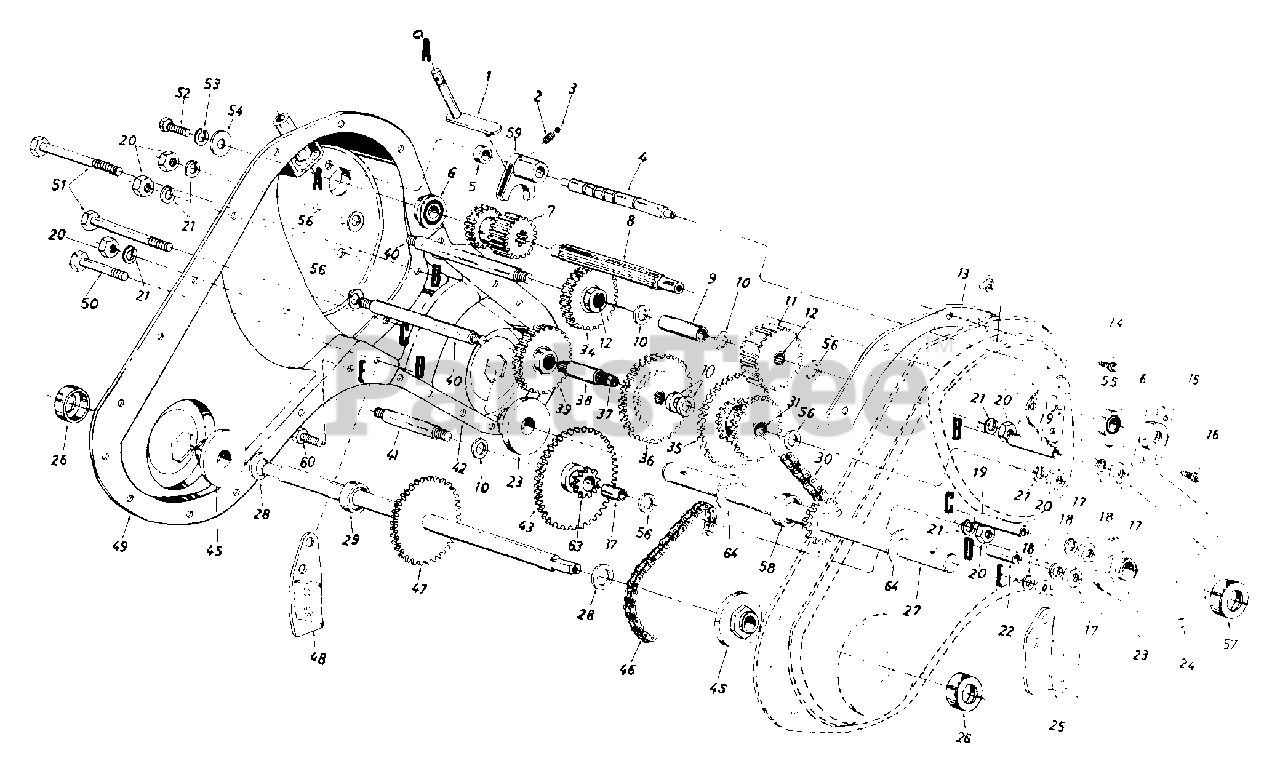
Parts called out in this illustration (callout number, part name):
1	Shifting Bracket Ass'y.
2	Compression Spring .50" Lg.
3	Ball Detent .250" Dia.
4	Detent Shaft 1/2" Dia.
5	Spacer .505" I.D. x .88" O.D.
6	Ball Brg. .62" I.D. x 1.38"
7	Spur Gear 16T (Input)
8	Input Spline Shaft 7/8"
9	Spacer .657" I.D. x 2.85" Lg.
10	Fl-Wash. .640" I.D. x 1.24"
11	Spur Gear 30T 7/8" I.D.
12	Needle Bearing 5/8" I.D.
13	Gasket - Trans. Hsg.
14	Hex S-Tap Scr. 1/4-20 x .5"
15	1-3/8" Dia. Bearing Housing
16	Hex TT-Tap Scr. 1/4-20 x .75"
17	Hex Nut 5/16-18 Thd.
18	L-Wash. 5/16" I.D.
19	Spacer 1.56" Lg.
20	Hex Nut 7/16-20 Thd.
21	Bell-Wash. .45" I.D. x 1.0"
22	Spacer 1.015" Lg.
23	Tine Shaft Brg. 1.002 x 2.50
24	Trans. Housing Ass'y. - L.H.
27	Tine Shaft Ass'y. 1" O.D.
28	Fl-Wash. .76" I.D. x 1.5" O.D.
29	Spacer .75" I.D. x .50" Lg.
30	Chain #50 5/8 Pitch x 52 Links - Endless
31	Needle Bearing 5/8" I.D.
32	Snap Ring
33	Taper Cap Plug
34	Spur Gear 30T 12/16" I.D
35	30/44T Gear Ass'y. Comp.
36	Spur Gear 44T
37	Sleeve Bearing
38	Gear Hub 3/4" I.D. x 3" Lg.
39	Spur Gear 30T 1.0" I.D. x 1/2" W
40	Jack Shaft 5/8" Dia. x 5"
41	Jack Shaft 5/8" Dia. x 2.38"
42	Trans. Housing Ass'y. - R.H.
43	Spur Gear 55T
45	Wheel Brg. .752" x 2.5"
46	#420 Chain 1/2 Pitch x 50 Links - Endless
47	Wheel Shaft Ass'y. 15.6"
51	Hex Bolt 5/16-18 x 2.5"
52	Hex Bolt 1/4-20 x .62" Lg.
53	L-Wash. 3/8" I.D.
54	Fl-Wash. 1/4" I.D. x .93" O.D.
55	Gear Positioner Bracket
56	Fl-Wash. 7/16" I.D. x 1-3/8"
57	Dust Cover Ass'y. 1" Shaft
58	Spacer 1" I.D. x 2" O.D.
59	Shifting Fork
60	Hex Bolt 5/16-18 x .75" Lg.
63	10T Sprocket Ass'y.
64	Thrust Wash. 1.03" I.D. x 1.62" O.D.
85	Gear Positioner Bracket
